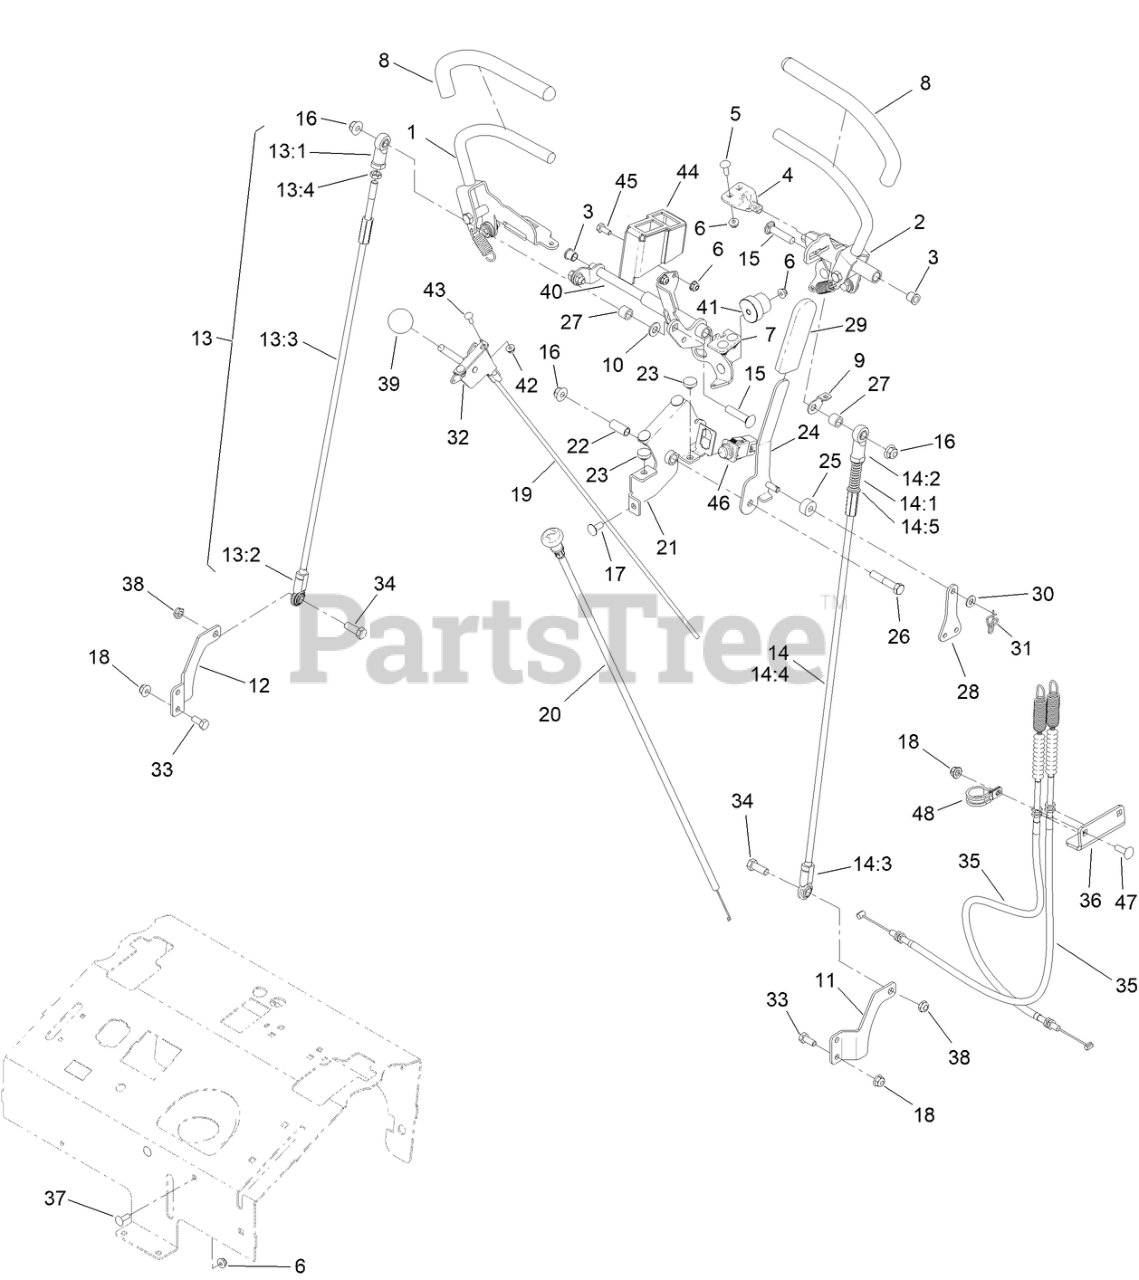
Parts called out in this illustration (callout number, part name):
1	RH CONTROL HANDLE ASM
2	LH CONTROL HANDLE ASM
3	BEARING
4	TAB-PIVOT, LH
5	BOLT-CARR
6	NUT-HF
7	TAB-PIVOT, RH
9	BRACKET-ADJUSTMENT, SPEED
10	WASHER-FLAT
11	BRACKET-HYDRO [BLK-TXT]
12	BRACKET-HYDRO [BLK-TXT]
13	RH CONTROL ROD ASM
13:1	END-ROD, FEMALE
13:2	JOINT-BALL END, LH
13:3	ROD-CONTROL
13:4	NUT-HJ
14	LH CONTROL ROD ASM
14:1	SPRING-RETURN, NEUTRAL
14:2	END-ROD, FEMALE
14:3	JOINT-BALL END, LH
14:4	ROD-CONTROL
14:5	WASHER-FLAT
15	SCREW-CARR
16	NUT-HF, NI
17	SCREW-CARR
18	NUT-HF, NI
19	CABLE-CONTROL
20	CABLE-CHOKE
21	BRACKET-BRAKE PIVOT (WELDED)
22	BEARING-SLEEVE
23	BUMPER
24	HANDLE-BRAKE ARM
25	BUSHING-BRAKE
26	SCREW-HH
27	SPACER
28	YOKE-CABLE
29	GRIP-LEVER
30	SPACER-NYLON
31	PIN-COTTER
32	LEVER-CONTROL
33	SCREW-HH
34	SCREW-HH
35	CABLE-BRAKE
36	BRACKET-CABLE, BRAKE
39	KNOB-BALL
40	PIVOT/PLATE SWITCH ASM (WELD)
42	NUT-LOCK, FLANGE
43	BOLT-CARR
44	BRACKET-SWITCH
45	SCREW-HH
46	SWITCH-PLUNGER
47	SCREW-CARR
48	CLAMP-R
